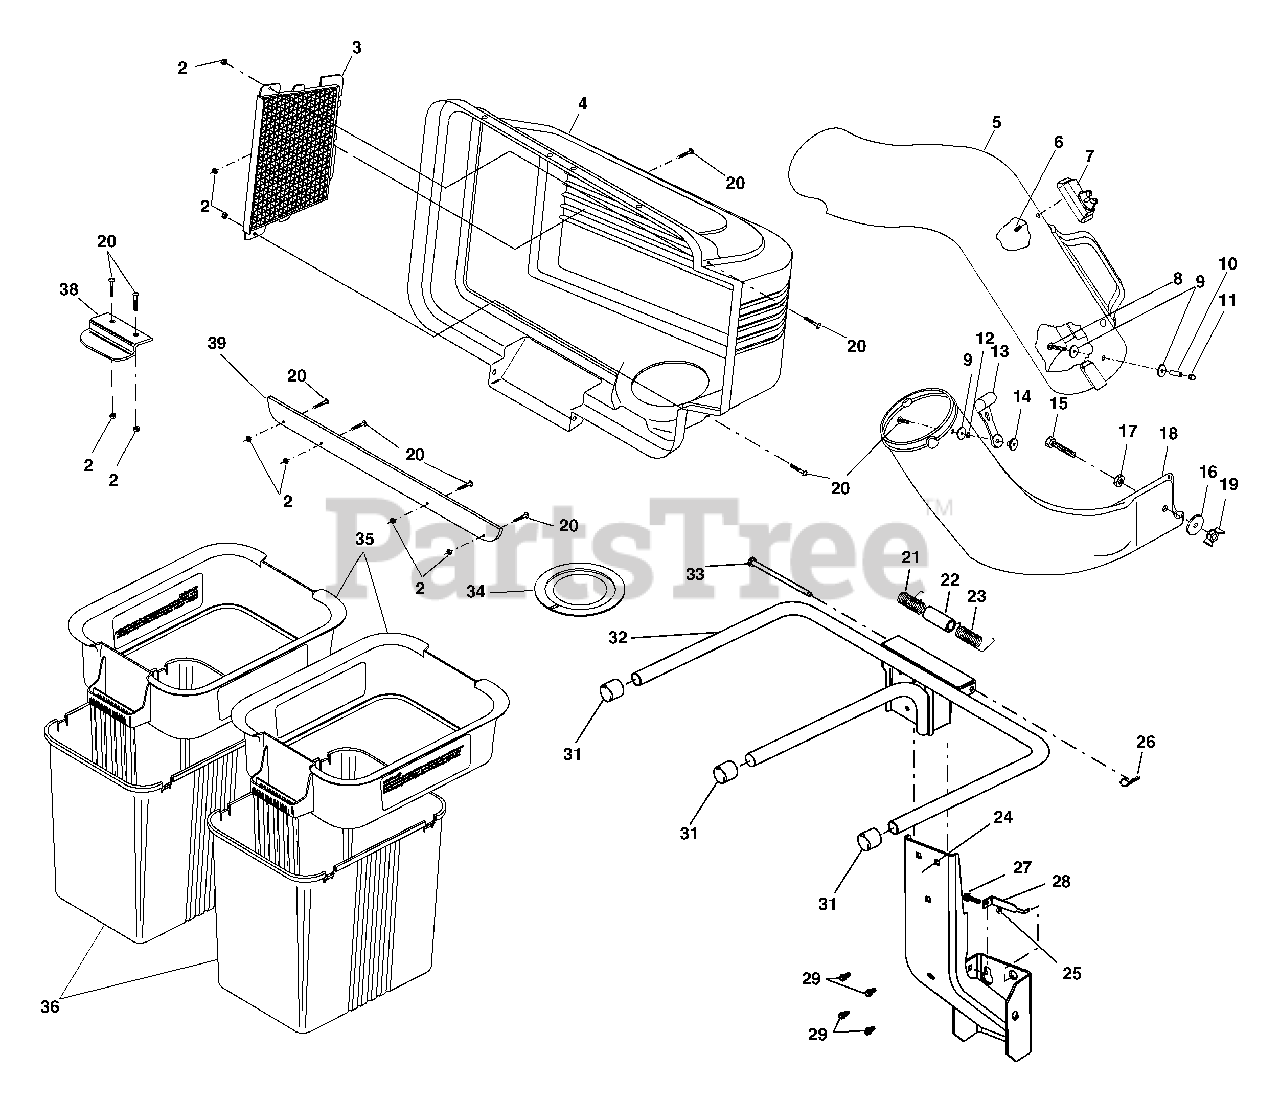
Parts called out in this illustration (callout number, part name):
2	Nut, Crown lock #10-24
3	Screen, Cover
4	Cover Asm.
6	Screw, Special
7	Dump Bag Indicator
8	Screw, #10-24 x 1-1/8
9	Washer 3/16x3/4x16 Ga.
10	Spacer, Split
11	Nut, Acorn #10-24
14	Nut, Weld
15	Bolt, Hex 3/8-16 x 1-1/4
16	Washer 13/32x1x16 Ga.
17	Locknut 3/8-16
19	Wingnut 3/8-16
20	Screw #10-24 x 5/8
21	Spring, Cover L.H.(black)
22	Spacer, Cover
23	Spring, Cover R.H. (gray)
24	Support Assembly
25	Locknut
26	Spring, Retainer
28	Bracket, Stop
29	Shoulder Bolt
31	Plug, Tubing End
32	Bagger, Frame
33	Pin, Hinge
34	Gasket, Cover
35	Container, Top
36	Container, Bottom
38	Latch Handle, Cover
39	Strip, Reinforcement
